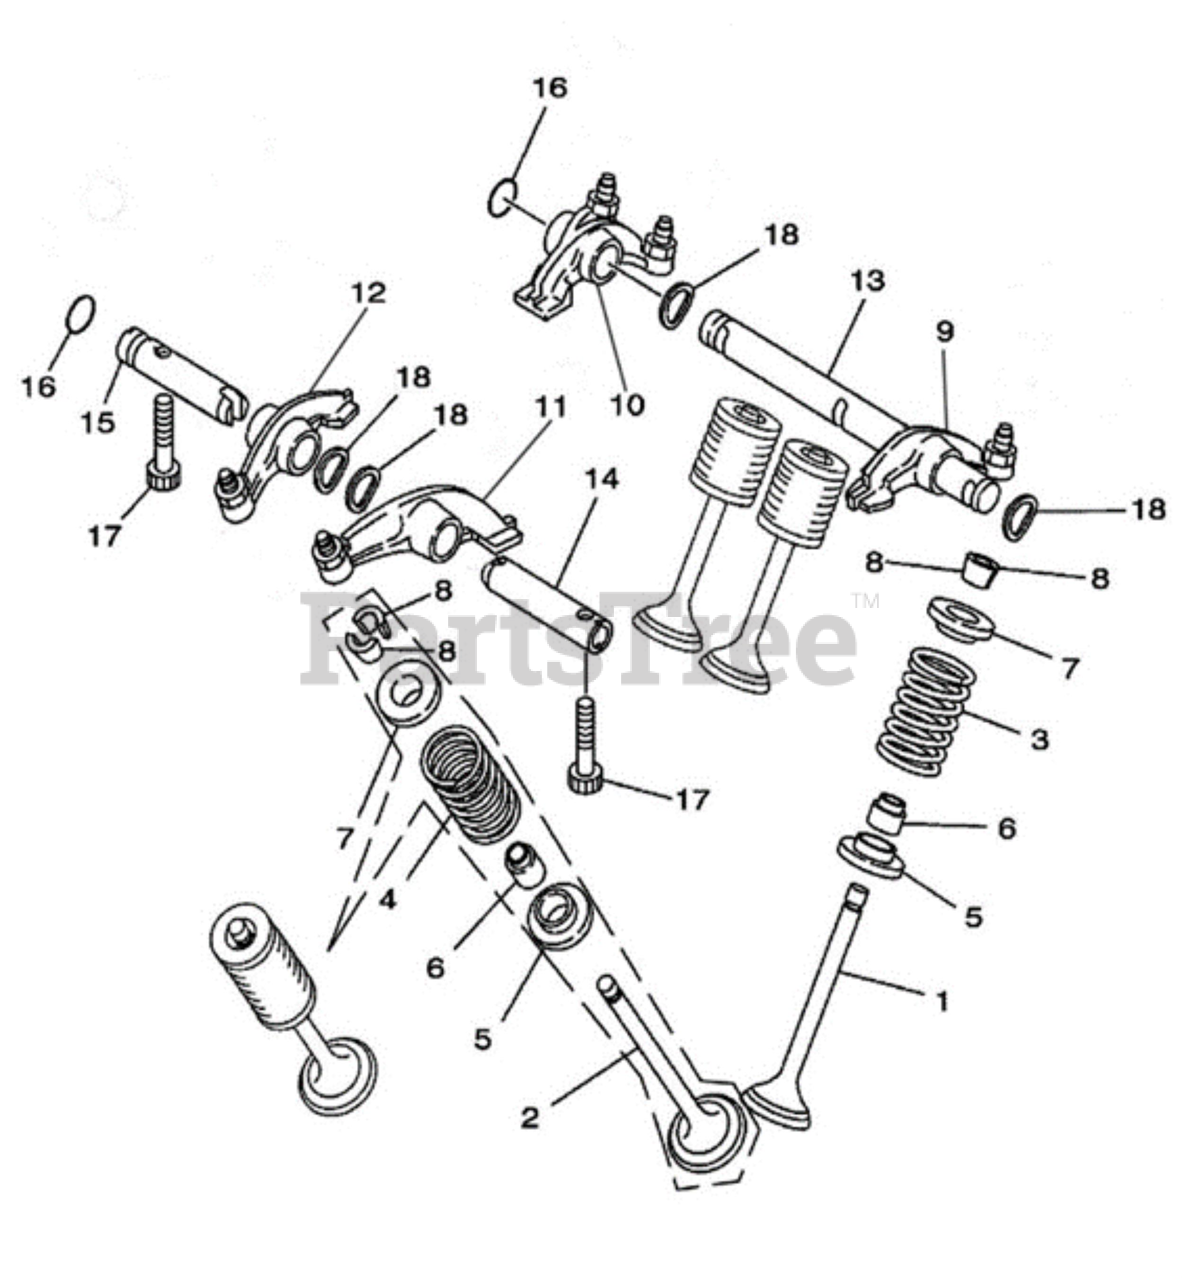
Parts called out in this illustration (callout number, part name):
1	Intake Valve
2	Exhaust Valve
3	Spring,Intake Valve
4	Spring,Exhaust Valve
5	Valve Spring Washer
6	Valve Stem Seal
7	Retainer,Valve Spring
8	Valve Lock Clamp
9	Intake Valve Rocker I?26?
10	Rocker Arm II?27?,Intake
11	Exhaust Valve Rocker?29?
12	Exhaust Valve Rocker ?28?
13	Intake Valve Rockershaft
14	Exhaust Valve Rockershaft
15	Exhaust Valve Rockershaft
16	O-Ring 9X2
17	Hexagon socket head cap screws M6X20
18	Wave Mode Washer 12.5X34X0.4
